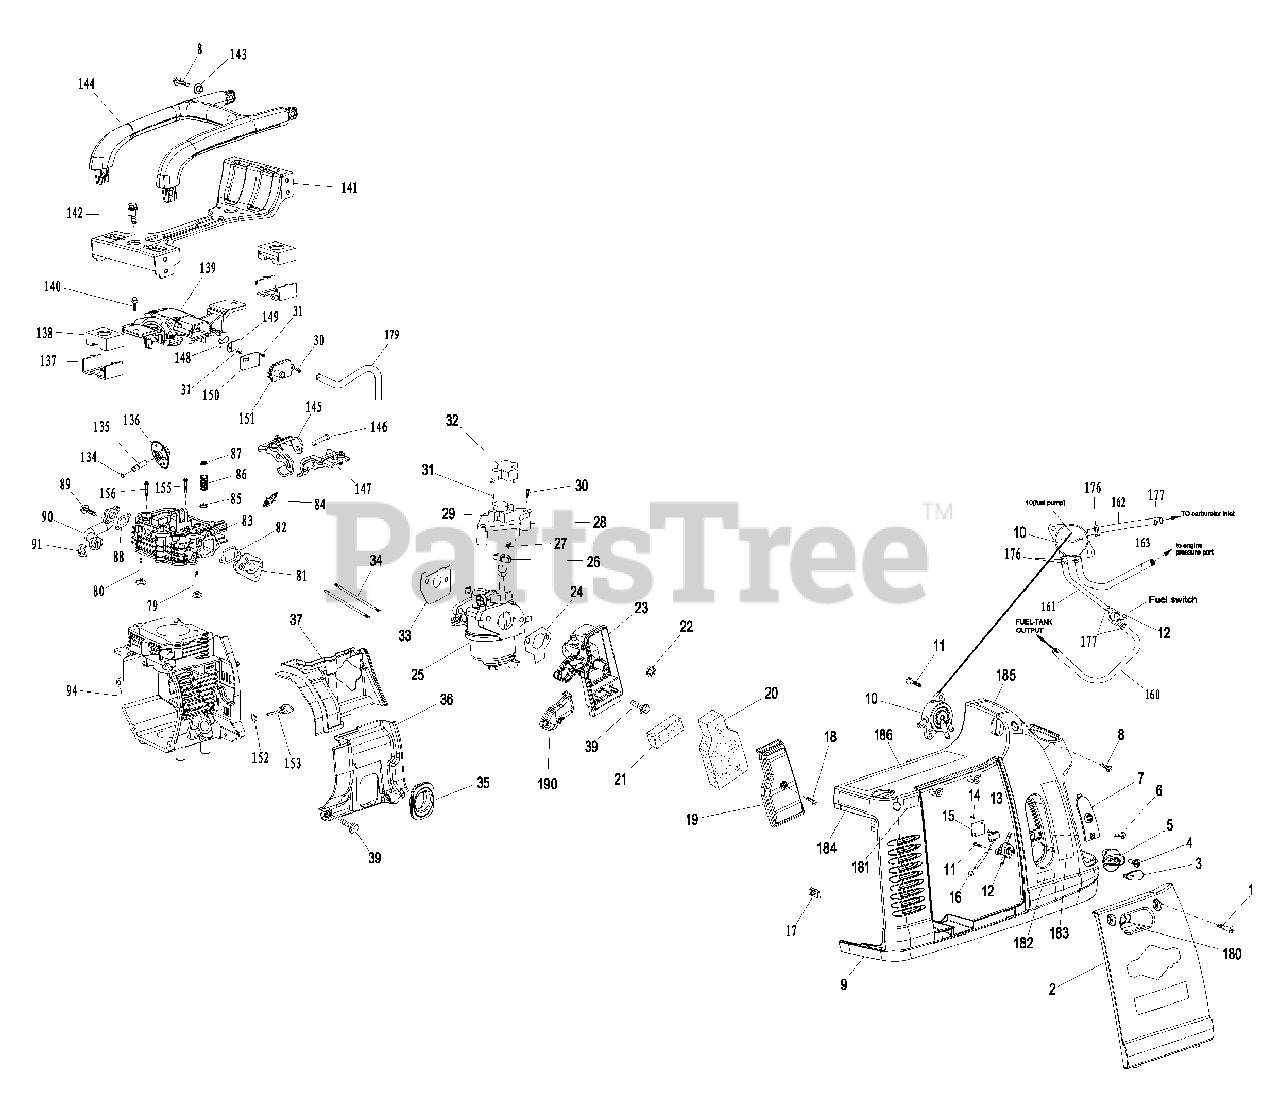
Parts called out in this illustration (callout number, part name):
4	BOLT
10	PUMP, Fuel
11	SCREW
14	BOLT
15	COVER, Switch
16	CONNECTION
17	*NUT
19	COVER, Air Cleaner
20	FILTER, A/C Foam
21	FILTER, A/C Foam
22	*NUT
23	BASE, Air Cleaner
24	GASKET, Air Cleaner
27	SPRING
30	BOLT
31	BOLT
35	SEAL, Rubber
36	DEFLECTOR
37	DEFLECTOR
79	VALVE, Intake
80	VALVE, Exhaust
83	CYLINDER HEAD
85	SEAL, Valve Oil
86	SPRING
87	SEAT, Valve
89	BOLT
90	MUFFLER
91	GASKET, Exhaust
94	CRANKCASE
134	O-RING
135	SHAFT
136	CAM ASSEMBLY
137	BRACKET
138	MOUNT, Vibration
139	COVER, Cylinder
140	BOLT
141	BRACKET
142	BOLT
145	ARM, Exhaust Valve
146	PIN
147	ARM, Intake Valve
148	VALVE
149	BOARD, Valve
150	BOARD, Valve
151	BOARD, Valve
176	CLAMP
177	CLAMP
190	COVER, Air Cleaner
